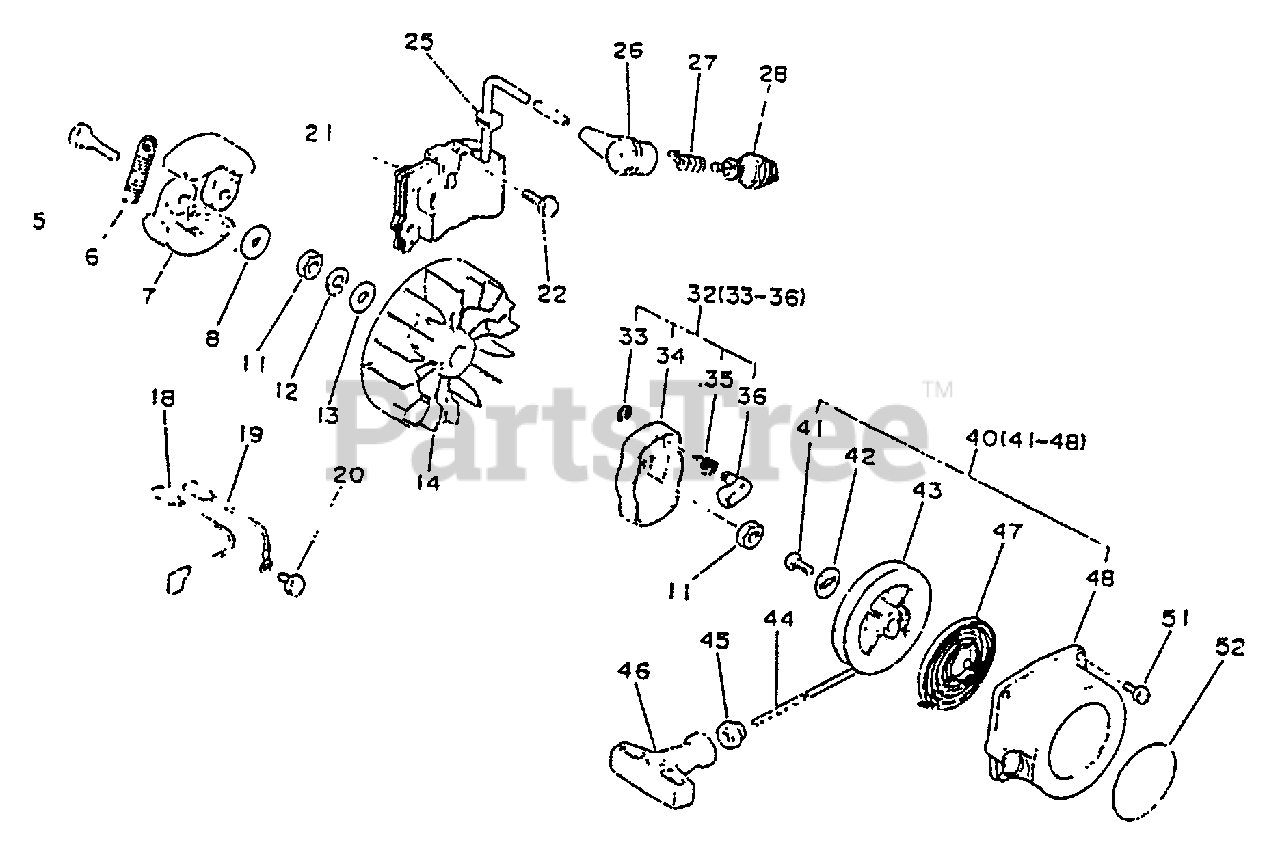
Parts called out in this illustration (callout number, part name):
5	BOLT, CLUTCH
6	SPRING, CLUTCH
7	SHOE, CLUTCH
8	WASHER 6.2×19×1.0
11	NUT 8×1.25
12	WASHER, SPRING 8
13	WASHER 8.5×16×1.2
14	FLYWHEEL
18	LEAD
19	LEAD - GROUND
20	SCREW 5×10
21	COIL, IGNITION
22	SCREW 5×20
26	CAP, SPARK PLUG
27	TERMINAL, SPARK PLUG
28	SPARK PLUG - BPM7A
32	PAWL ASSY, STARTER
33	E-RING 4
34	CATCHER, PAWL
35	SPRING, RETURN
36	PAWL, STARTER
40	STARTER ASSY
42	WASHER
43	REEL, ROPE
44	ROPE, STARTER 3.5×850
45	GUIDE, ROPE
46	GRIP, STARTER
47	SPRING, RECOIL
48	CASE, STARTER
51	SCREW 4×14
52	LABEL, ECHO
